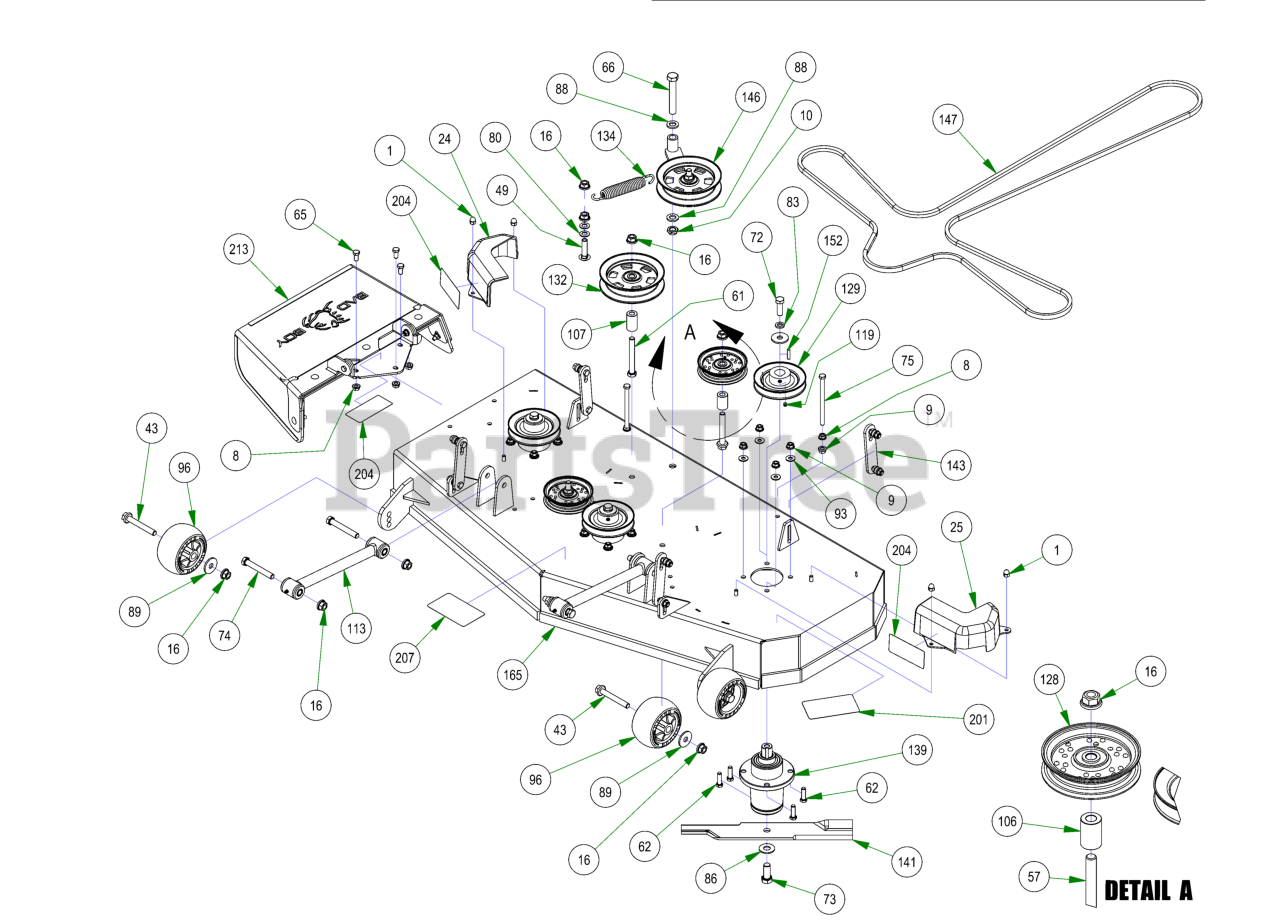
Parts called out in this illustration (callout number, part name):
1	5/16-18 ACORN NUT HIGH-CROWN ZC
8	3/8-16 HEX SERRATED FLANGE NUT HARD/ZINC
9	3/8-16 NYLON INSERT FLANGE LOCKNUT (GR.F) ZINC
10	5/8-11 NYLON INSERT JAM LOCKNUT ZINC
16	1/2-13 NYLON INSERT FLANGE LOCKNUT ZINC
24	pulley cover chute side
25	pulley cover non-chute side
43	1/2-13 X 90MM HEX FLANGE BOLT W/SHOULDER (GR.8) ZINC
49	1/2-13 X 2 CARRIAGE BOLT ZINC
57	1/2-13 X 3-1/2 HEX FLANGE BOLT (GR.8) ZINC
61	1/2-13 X 4 HEX CAP SCREW (GR.8) ZINC YELLOW
62	3/8-16 X 1-1/4 HEX CAP SCREW (GR.5) ZINC
65	3/8-16 X 3/4 HEX CAP SCREW (GR.5) ZINC
66	5/8-11 X 4 HEX CAP SCREW (GR.8) ZINC YELLOW
72	1/2-20 X 1-1/2 HEX CAP SCREW (GR.5) ZINC
73	5/8-18 X 1-1/2 HEX CAP SCREW (GR.8) ZINC YELLOW
74	1/2-13 X 3-1/2 HEX CAP SCREW (GR.5) ZINC
75	3/8-16 X 5-1/2 HEX CAP SCREW (GR.5) ZINC
80	.517 SQ WDTH ID X .937 OD X .060 THICK F/W PHOS/OIL
83	1/2 SPLIT LOCKWASHER (GR.8) ZINC/YELLOW
86	5/8 USS FLAT WASHER (1-3/4" OD) GR.8 ZINC YELLOW
88	.635 ID X 1.120 OD X .140 THICK FLAT WASHER NYLON
89	1/2 BELLEVILLE WASHER (1-5/8 OD X .140 THK) ZINC
93	5/16 USS FLAT WASHER (7/8 OD) ZINC
96	Deck Wheel
106	.502 ID X .750 OD X 1.500 Long Spacer
107	1 3/4" Pulley Spacer
113	Hybrid Turnbuckle/Deck Locator
119	5/16-24 X 1/4 SOCKET SET SCREW (CUP PT) PLAIN
128	4 3/4 Idler Pulley - ABFI-76
129	5" Spindle Deck Pulley
132	5-3/4 Idler Pulley
134	Deck Idler Spring
139	Spindle Assembly
141	48" ZT/Mav/Compact Outlaw Blade with Fusion
143	Deck Hanger Assembly
146	2017 54"/48" Deck Idler Assembly
147	B147 Deck Belt
152	1/4 X 1 SQ MACHINERY KEY 1018 STL PLN
165	2017 48" ZT Deck Welded Assembly
201	2018 48" Deck Decal
204	Danger Decal-Spindle/Discharge
207	Deck Belt Route Decal
213	ZT Chute Assembly
